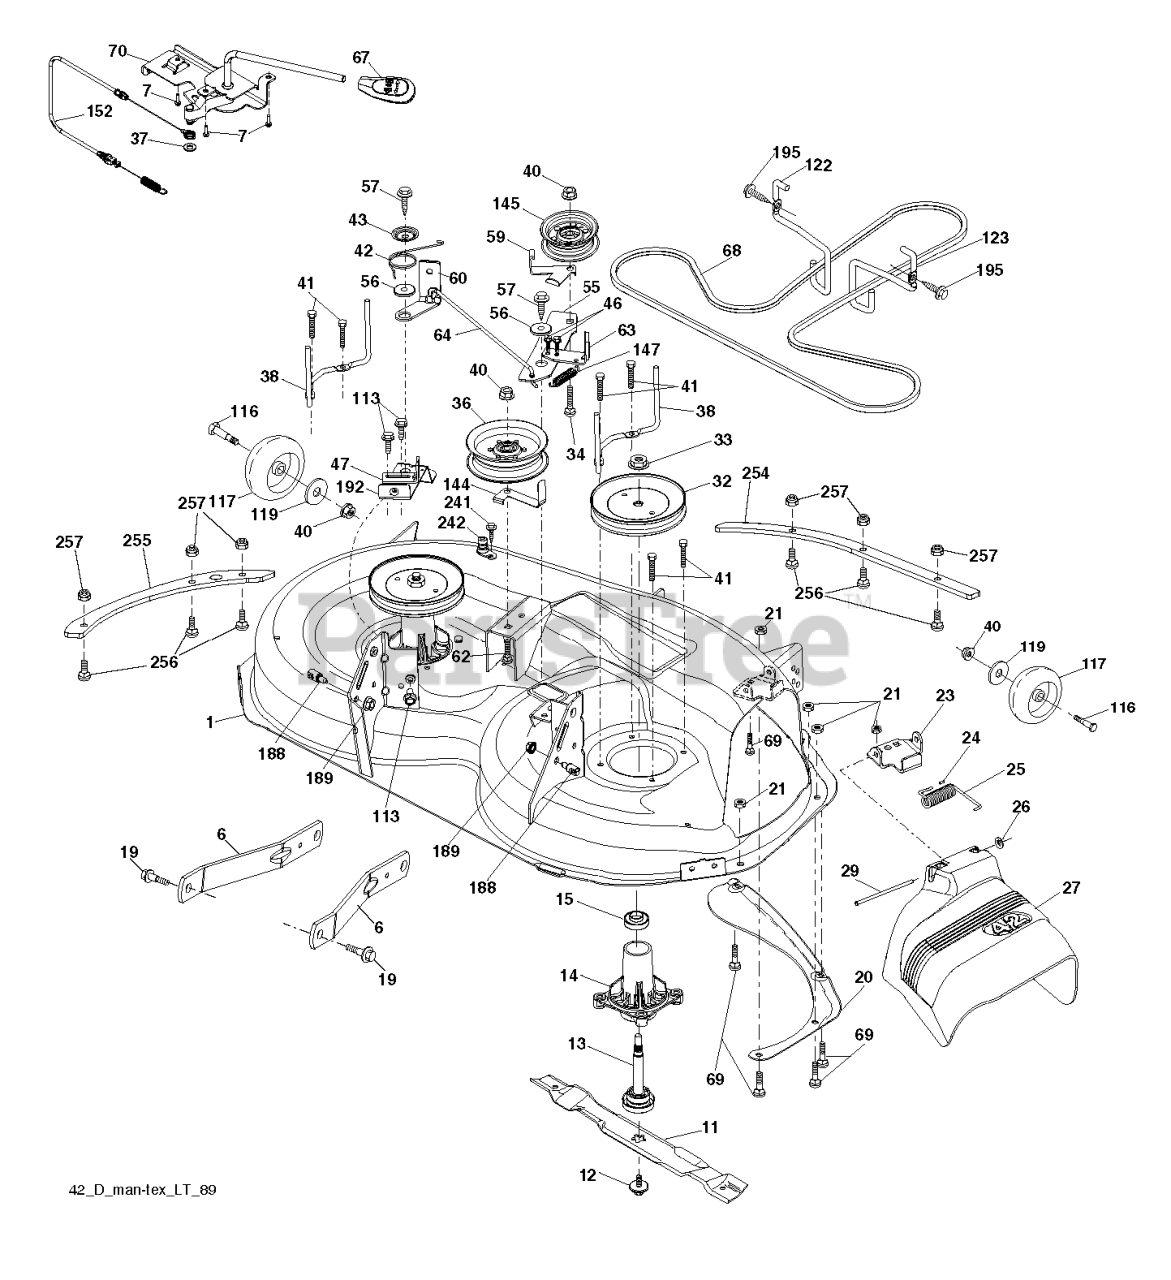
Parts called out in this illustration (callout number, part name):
1	REPAIR KIT KIT.SRV.WLDMENT.42
6	ARM.SUSPENSION.MOWER.R
7	SCREW.#10 X 0.750.BOS
11	42" HI-LIFT BLADE
12	SCREW.SEMS.7/16-20X1.HEX.HEAD
13	SHAFT ASM.MNDRL.N/GREASEABLE
14	RP.HOUSING.MANDREL.4PT.
15	BEARING.MANDREL.TOP.EXTENDED
19	BOLT.SHOULDER
20	BAFFLE.VORTEX
21	LOCKNUT
23	BRKT.DEFLECTOR.38"2005+
24	CAP-SLEEVE LT
25	SPRING.TORSION.DEFLECT
26	NUT PUSH M
27	SHIELD.DEFLECTOR.MOWER.42"BLAC
29	ROD.HINGE
32	PULLEY.MANDREL.5.438.PD
33	NUT.FLANGE.LOCK.TOP
34	BOLT.3/8-16X1.50
36	PULLEY.IDLER.2006
37	WASHER
38	KEEPER.BLT.PNT.MNDRL.PULL.6.25
40	NUT LOCK FLG 3/8-16 UNC
41	BOLT.HEX.WASHR.HED.313-18X1.19
42	SPRING.TORSION.BRAKE
43	SRPING.TORSION.RETAINE
46	SCREW.1/4-20X5/8
47	BRKT.CLUTCH.CABLE
55	IDLER.ARM.42"
56	SPACER.RETAINER
57	SCREW 3/8-16X1
59	GUARD, BELT
60	ARM BRAKE MOWER
63	ARM BRAKE MOWER
64	LINKAGE.BRAKE.ASM.ZINC
67	HANDLE.CLUTCH.CABLE.LT
68	BELT.DECK.DRIVE.42"
69	BOLT
70	CLUTCH.ASM.MANUAL.YT.PREDATORQ
113	BOLT.5/16HEX.WHS.HD
116	BOLT M
117	WHEEL.GAUGE.RALLY.NARROW
119	WASHER.5/16.FLAT.STE.STD.
122	KEEPER BELT ENGINE LH
123	KEEPER BELT RH
144	KEEPER.BELT.MOWER
145	PULLEY.IDLER.48"PRIMARY
147	RETURN SPRING
152	CABLE.MECHANICAL.CLUTCH
188	STUD.FASTNER.W/ANTI-ROTATE
189	NUT LOCK HEX FLANGE 5/16-18
192	BRKT.BRAKE.STAND.LH.
195	SCREW, 3/8-16X3/4
241	SCREW.TT.#10-32X.5.3/8.FLANGE
242	PORT.WASHOUT
254	PLATES.RENFRC.42DECK.PT431FRNT
255	PLATES.RENFRCE.42DECK.X431SIDE
256	BOLT CUP HEAD SQUARE NECK 1/4-
257	NUT T
